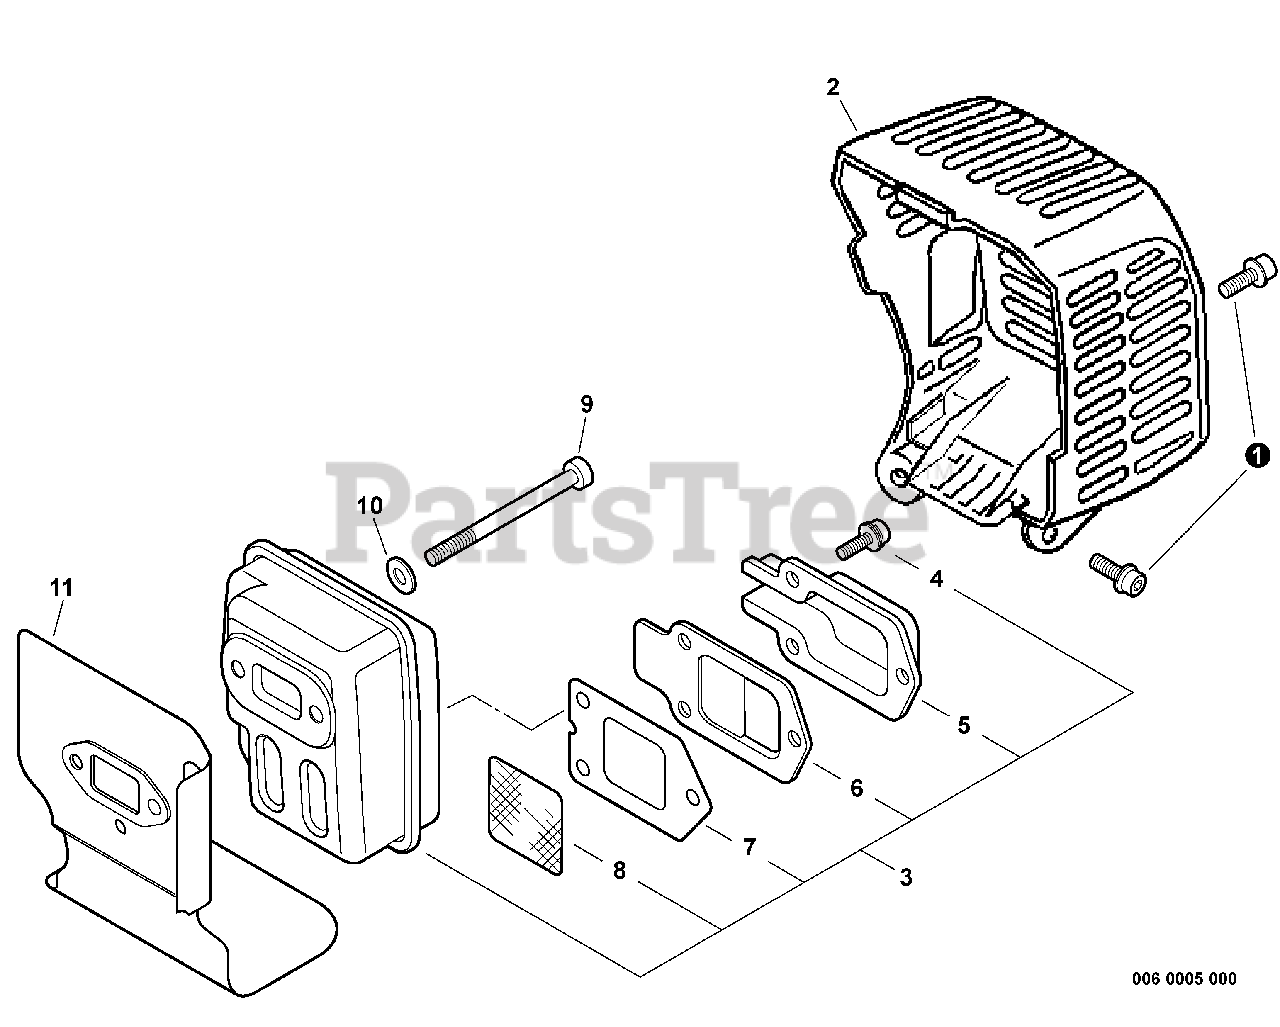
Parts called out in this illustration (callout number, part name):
1	COVER, MUFFLER
2	BOLT 5×12
3	MUFFLER ASSY
4	SCREW 4×10
5	GUIDE, EXHAUST
6	GUIDE, EXHAUST
7	GASKET, EXHAUST
8	SCREEN, SPARK ARRESTER
9	BOLT 5×55
10	WASHER 5.3×10×1
11	HEAT SHIELD, EXHAUST
